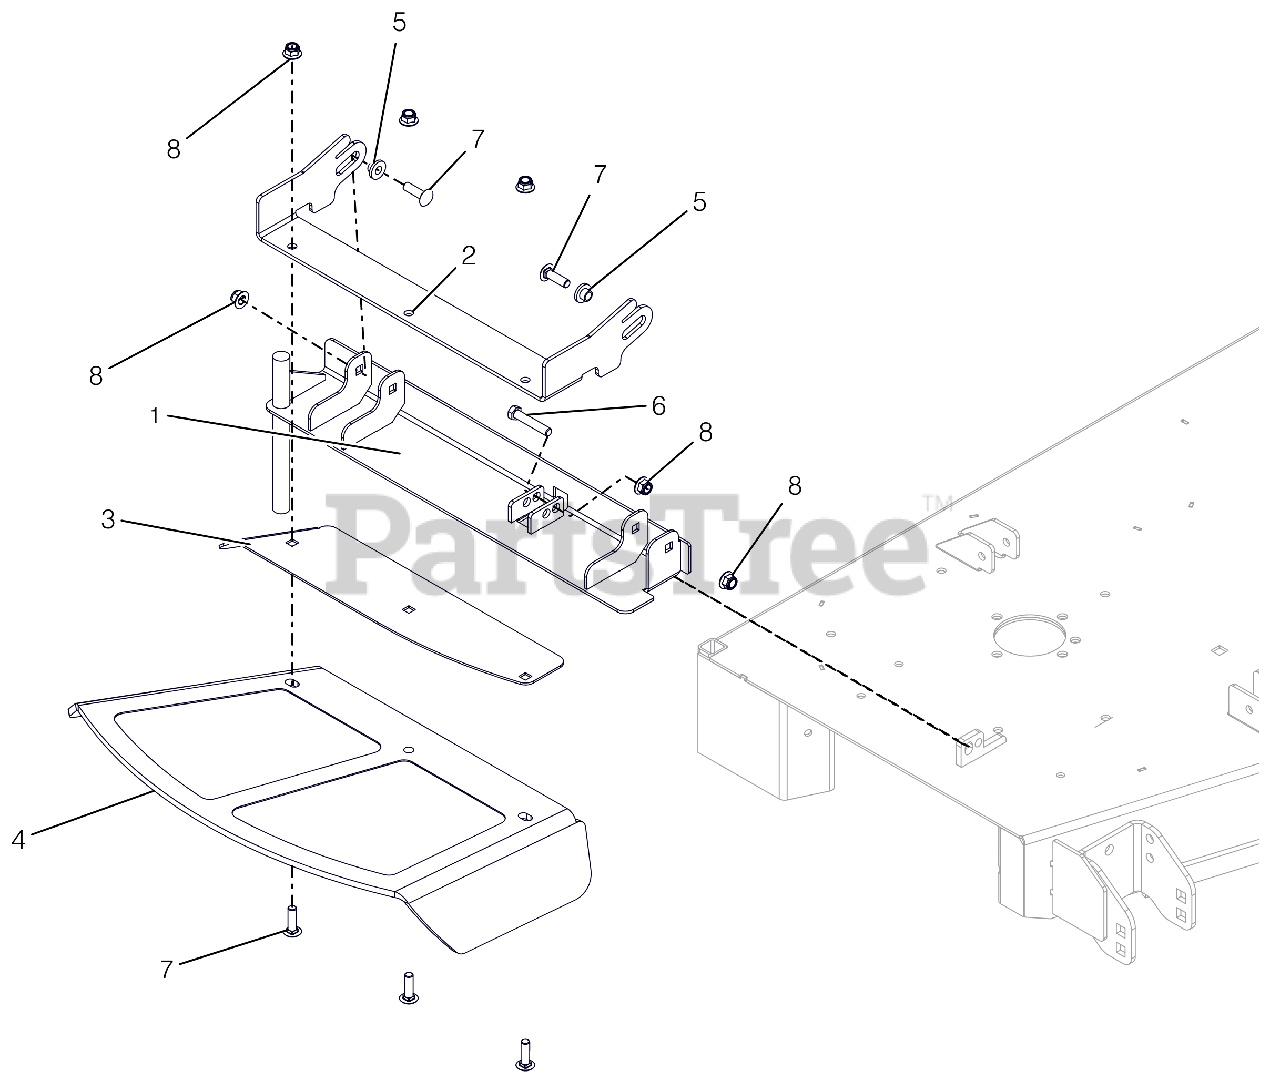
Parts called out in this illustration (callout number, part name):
1	44-60 DISCH CHT WMT ORG W/SAFE
2	48-60" CHUTE MTG BRKT -ORG
3	48-60 DISCH CHUTE CLMP PLT-ORG
4	CHUTE,48-60" FRMD RUBBER DISCH
5	BSHG-FLG .385X.500X.875X.406
6	@BLT-HEX .38-16X2.00 GR5 YWZC
7	@BLT-RHDSSQNK .38-16X1.25 G5YZ
8	@NUT-LK-NYL-FLG .38-16 YWZC
